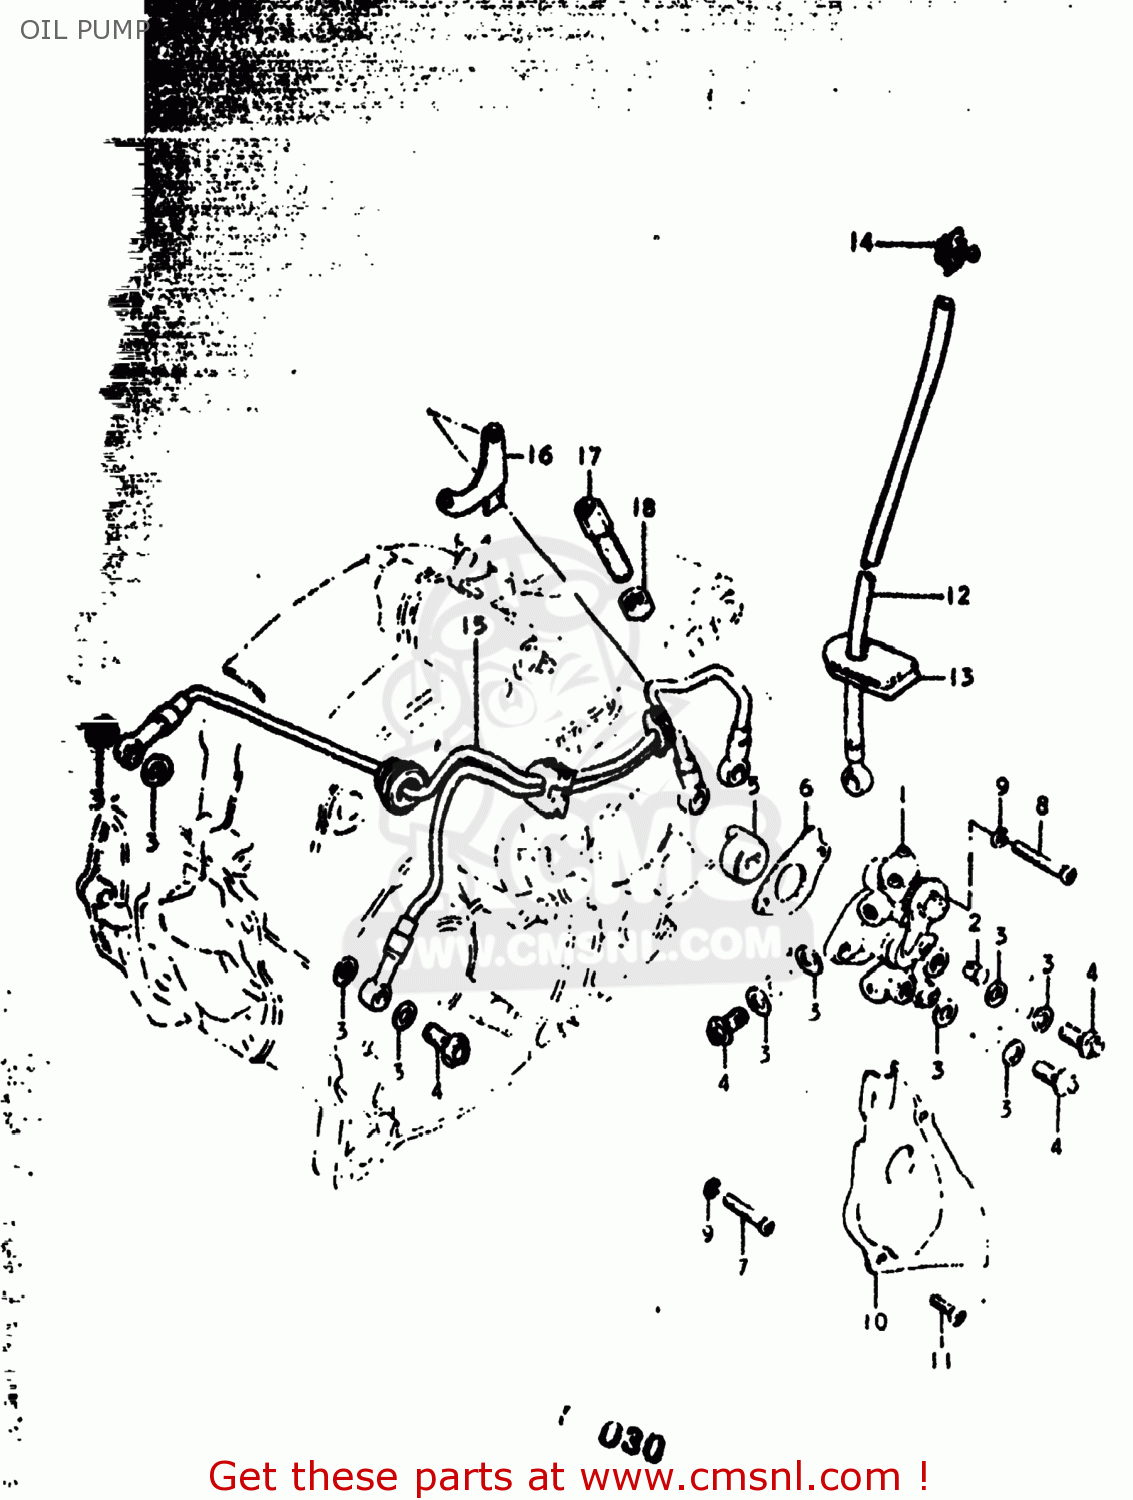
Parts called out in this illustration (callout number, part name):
1	PUMP ASSEMBLY,OIL
2	TERMINAL,CABLE
3	GASKET (NAS)
4	UNION BOLT
5	PIECE,OIL PUMP DRIVE
6	GASKET,OIL PUMP (MCA)
7	SCREW
8	SCREW
9	LOCK WASHER
10	CAP,OIL PUMP INSPECTION
11	SCREW
12	HOSE,OIL NO.1
13	GROMMET
14	CLAMP
15	HOSE,OIL NO.2
16	CLAMP
17	BOLT
18	NUT
